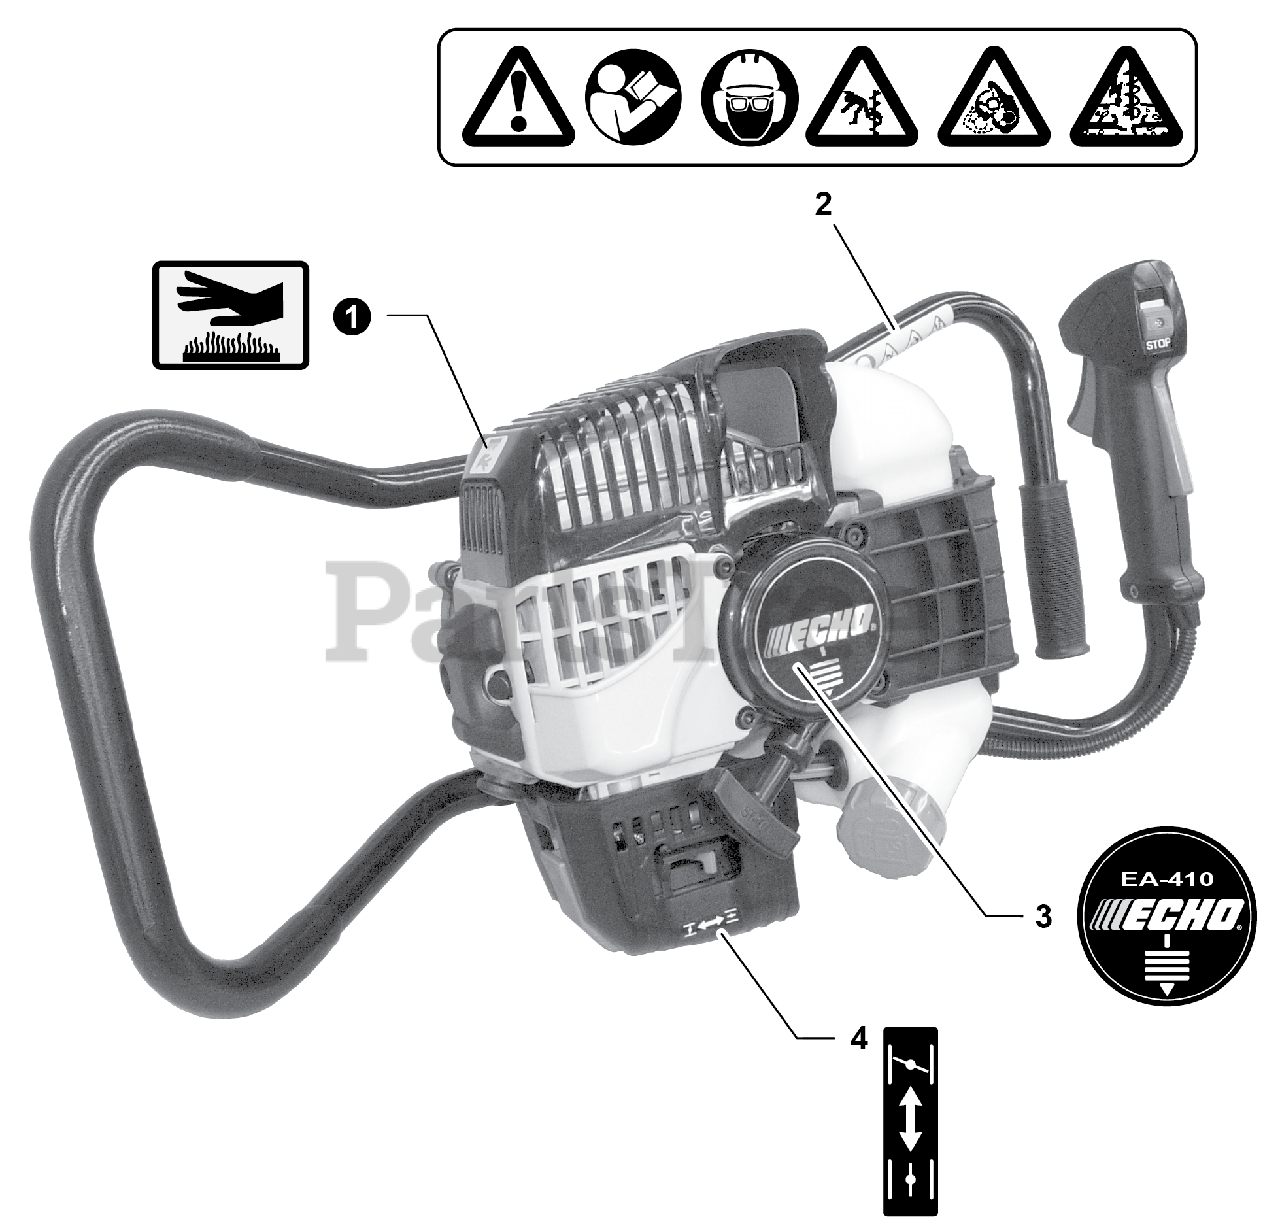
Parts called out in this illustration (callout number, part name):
1	LABEL, CAUTION - HOT
2	LABEL, CAUTION
3	LABEL, EA-410
4	LABEL, CHOKE
